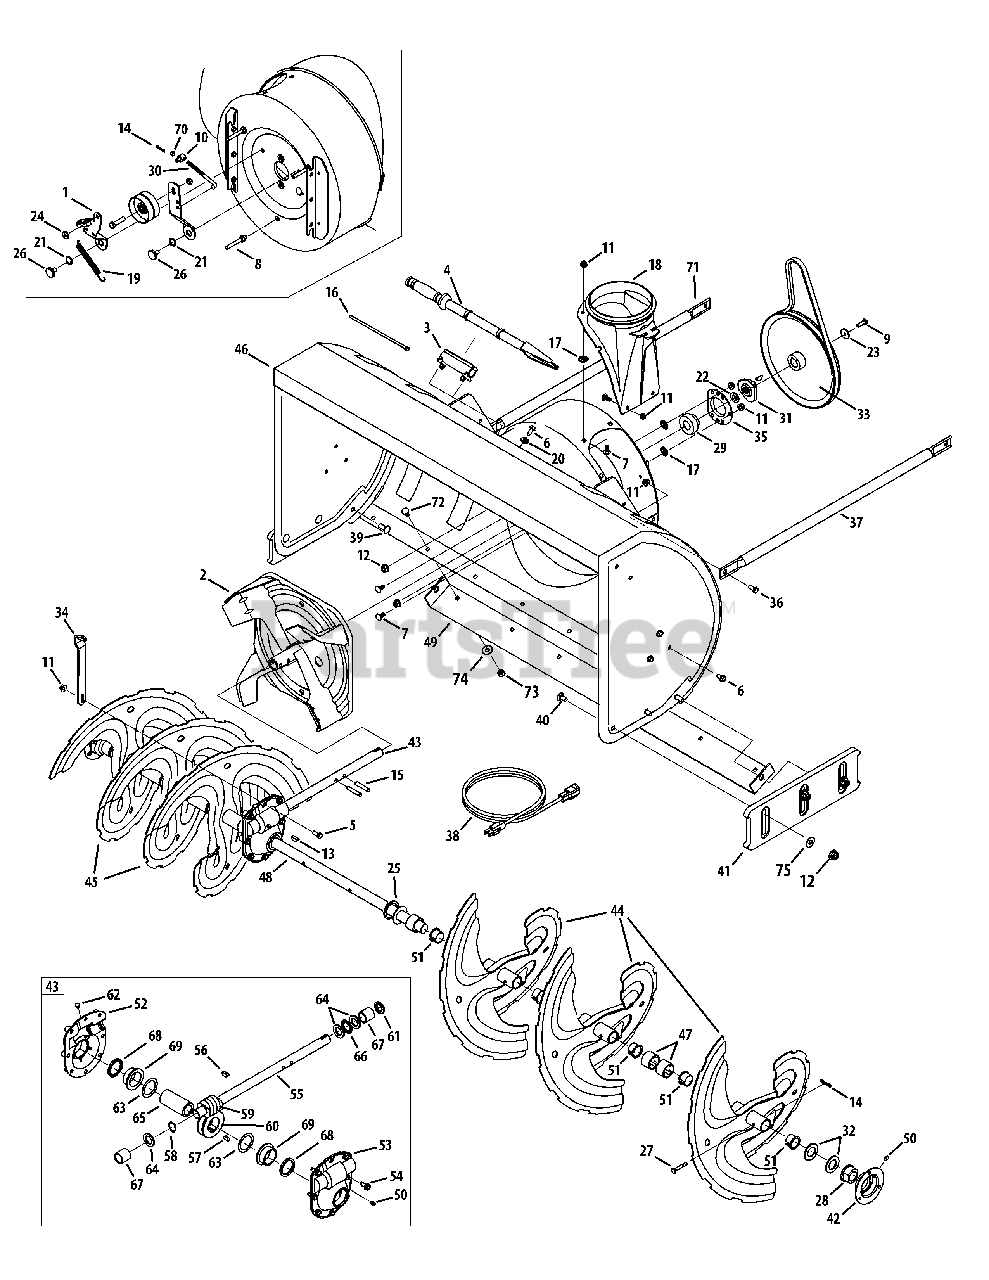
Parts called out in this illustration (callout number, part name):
1	Bracket Assembly, Auger Brake
2	Impeller , 16"
3	Clip, Mounting
4	Tool, Clean-out
5	Screw, Hex Cap, 5/16-18 x 1.0 Gr5
6	Screw, 5/16-18 x .750
7	Screw, Carriage, 5/16-18 x .75
8	Screw w/Stud, 5/16-18 x .4300
9	Screw, Hex Cap Lock, 5/16-24, 875
11	Nut, Hex Flange Lock, 5/16-18
12	Nut, Hex Flange Lock, 3/8-16
13	Key, Woodruff, 1/4 x 3/4
14	Pin, Bow-tie Cotter
15	Pin, Spiral, 5/16 x 1.75
16	Cable Tie
17	Nut, Push
18	Adapter, Chute, 6"
19	Spring, Extension
20	Washer, Flat, .349 x .879 .063
21	Washer, Wave, .625 x .885 x .015
22	Washer, Bell., .78 x 1.49 x .06
23	Washer, Flat, .34 x 1.5 x .15 Ht.
24	Washer, .344 x .75 x .12
25	Washer, 1.01 x 1.86 x .06
26	Screw, Shoulder, .625 x .17
27	Pin, Shear, .25 x 1.75
28	Bearing, Flange w/Flats
29	Bearing, Self Aligning
30	Rod, Auger Idler
31	Adapter, Pulley w/Pins
32	Spacer, 1.004 x 1.375 x .25
33	Pulley, Auger Drive, 10.0
34	Bracket, Gear Box Support
35	Housing, Bearing
36	Screw, 5/16-18 x .75 GR5
37	Tube, Support , LH
38	Extension Cord, 110V
39	Screw, Carriage, 3/8-16 x .75
40	Screw, Carriage, 3/8-16 x 1.00
43	Gear Box Assembly
47	Spacer, 1.50 x 1.00 x 1.00
48	Axle, Spiral
49	Shave Plate, 45"
50	Grease Fitting, 3/16
51	Flange Bushing
52	Housing Assembly, Auger, RH
53	Housing Assembly, Auger, LH
54	Screw, LD, 5/16-18 x .750
55	Auger Drive Shaft
56	Key, Hi Pro, 3/16 x 3/4
57	Key, 1/4 x 3/4 Dia.
58	External Retainer Ring
59	Gear, Worm
60	Gear, Worm, LH
61	Seal, Oil
63	Wash, Flat, 1.52ID x 2.0 OD
64	Wash, Flat, .88 ID x .38 OD
65	Worm Gear Shaft
66	Bearing, Thrust
69	Flange Bearing
70	Jam Nut, 5/16-18
71	Tube, Support, RH
72	Screw, Carriage, 5/16-18 x .750
73	Nut, Hex, 5/16-18
74	Washer, Bell., .34 x .872 x .060
75	Washer, Flat, .385 x .870 x .092
